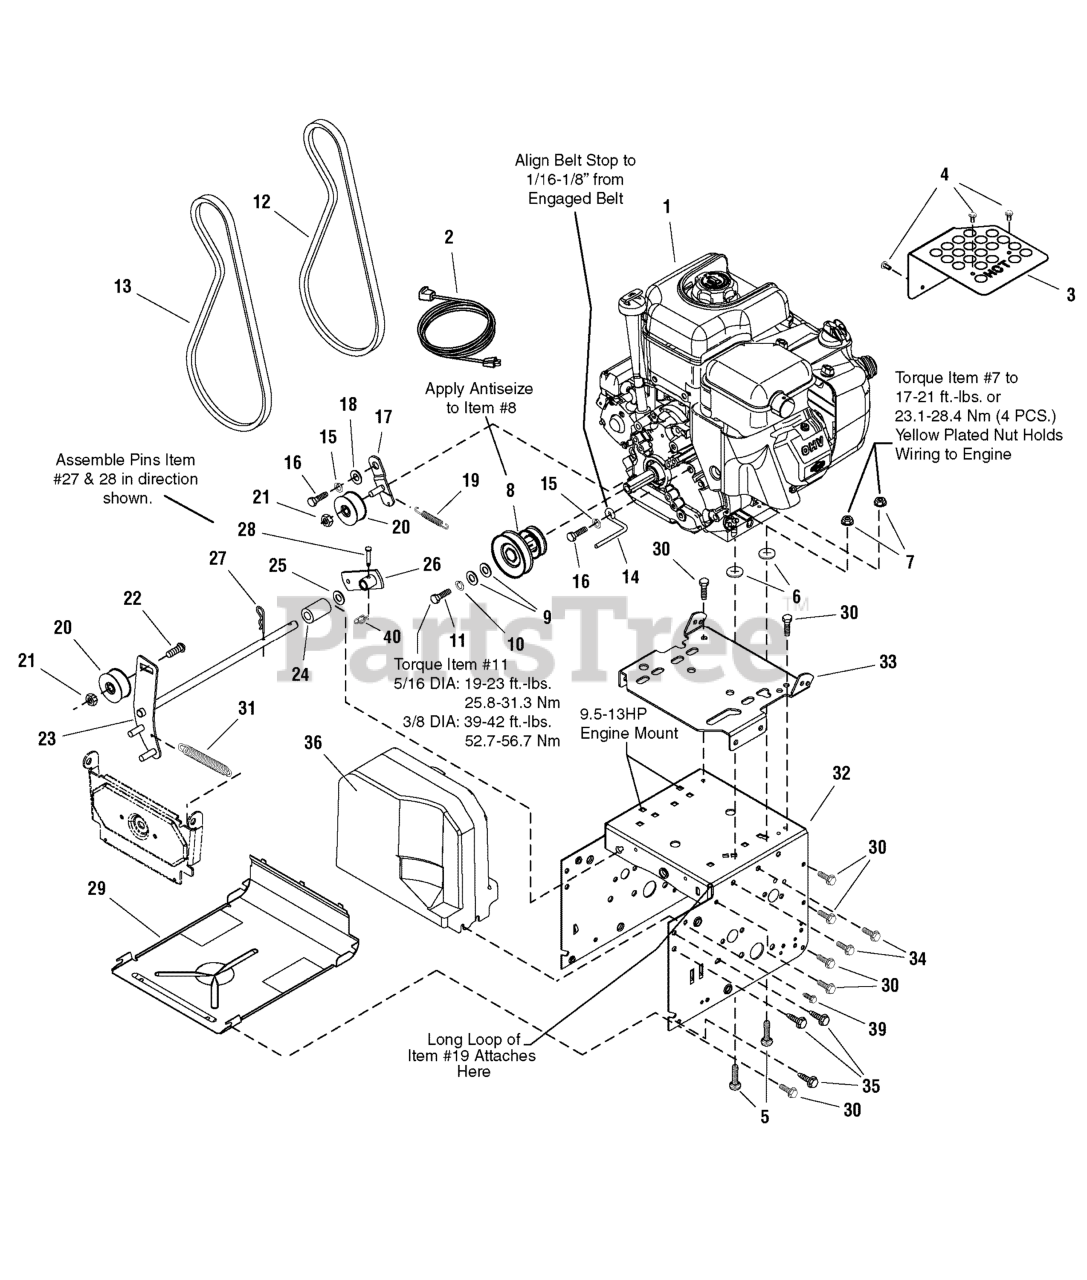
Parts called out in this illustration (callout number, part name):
1	ENGINE, BRIGGS & STRATTON *
2	CORD, Electric Start
3	GUARD, Muffler
4	SCREW, Hex Washer Head Taptite, 10-24 x 3/8
5	CARRIAGE BOLT
6	NUT, Speed
7	NUT, Hex Flange, 5/16-18 Whiz Lock Small
8	PULLEY, Engine
9	WASHER, 5/16
10	LOCKWASHER, Spring 3/8
11	CAPSCREW, Hex Head, 3/8-24 x 1-1/4 G8
12	V-BELT, Drive
13	V-BELT, Auger
14	STOP, Belt
15	LOCKWASHER, Spring 5/16
16	CAPSCREW, Hex Head, 5/16-24 x 3/4 G5
17	IDLER BRACKET ASSEMBLY, Drive Belt
18	BUSHING, Idler Bracket
19	SPRING, Extension Idler
20	IDLER, Plastic Ball Bearing
21	NUT, Hex Jam, 3/8-16
22	CARRIAGE BOLT, 3/8-16 x 1-1/4
23	IDLER ASSEMBLY, Auger
24	SPACER, Auger Idler
25	WASHER, 1/2
26	BRACKET & HUB ASSEMBLY, Spring
27	PIN, Hair
28	PIN, Clevis
29	PANEL, Bottom
30	SCREW, Hex Washer Head Taptite, 1/4-20 x 5/8
31	SPRING, Extension Auger Idler
32	FRAME BOX
33	PLATE, Engine Mount
34	SCREW, Hex Washer Head Taptite, 5/16-18 x 1/2
35	SCREW, Hex Washer Head Taptite, 5/16-18 x 3/4
36	COVER, Belt
39	SCREW, Hex
40	PIN, Cotter, Self Lock, .25
